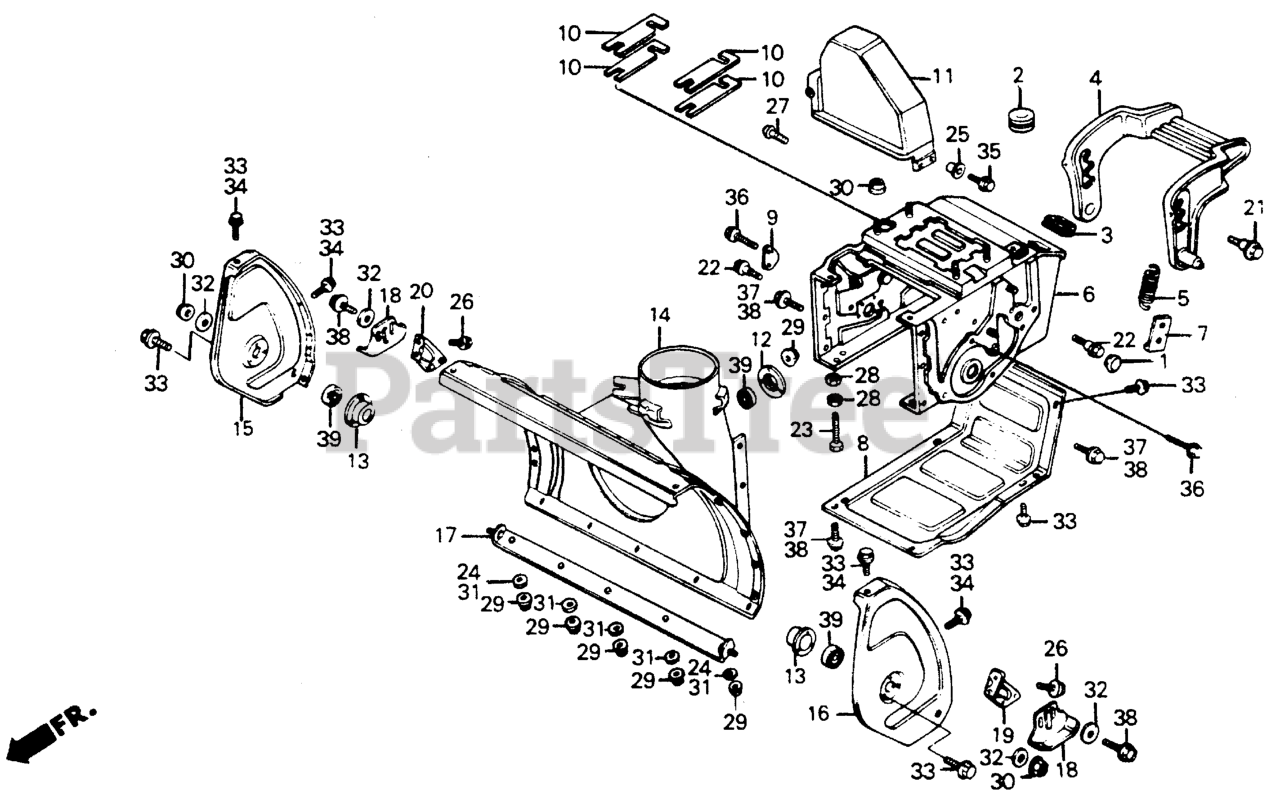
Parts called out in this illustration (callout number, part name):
1	GROMMET, GUIDE ROLLER (NOT AVAILABLE)
2	GROMMET A, TUBE
4	PLATE, HEIGHT ADJUSTING (NOT AVAILABLE)
5	SPRING, HEIGHT ADJUSTING
6	BED, ENGINE
7	HOOK, SPRING (NOT AVAILABLE)
8	COVER (LOWER) (NOT AVAILABLE)
9	PLATE, DISK HOLDER SHAFT
10	SPACER, MOUNTING
11	COVER, BELT (NOT AVAILABLE)
12	HOLDER, L. AUGER
13	HOLDER, AUGER BEARING
14	HOUSING, AUGER (12")
15	COVER, R. AUGER SIDE
16	COVER, L. AUGER SIDE (NOT AVAILABLE)
17	GUARD, AUGER HOUSING
18	SKID, AUGER
19	STAY, L. SKID
20	STAY, R. SKID
21	BOLT, HEIGHT ADJUST SETTING
22	BOLT, TRANSMISSION SETTING
23	BOLT, ADJUSTING
25	WASHER, CHAIN CASE SETTING
26	BOLT-WASHER (6X14)
27	SCREW, PAN (6X18)
28	NUT,HEX 8MM
29	NUT, FLANGE (6MM)
30	NUT, FLANGE (8MM)
31	WASHER, PLAIN (6MM)
32	WASHER, PLAIN (8MM)
33	BOLT, FLANGE (6X10)
35	BOLT, FLANGE (6X12) Use up to Engine SN 1543277.
36	BOLT, FLANGE (6X18)
37	BOLT, FLANGE (8X14)
38	BOLT, FLANGE (8X16) Use from Engine SN 1000016.
39	BEARING, RADIAL BALL (6203UU)
